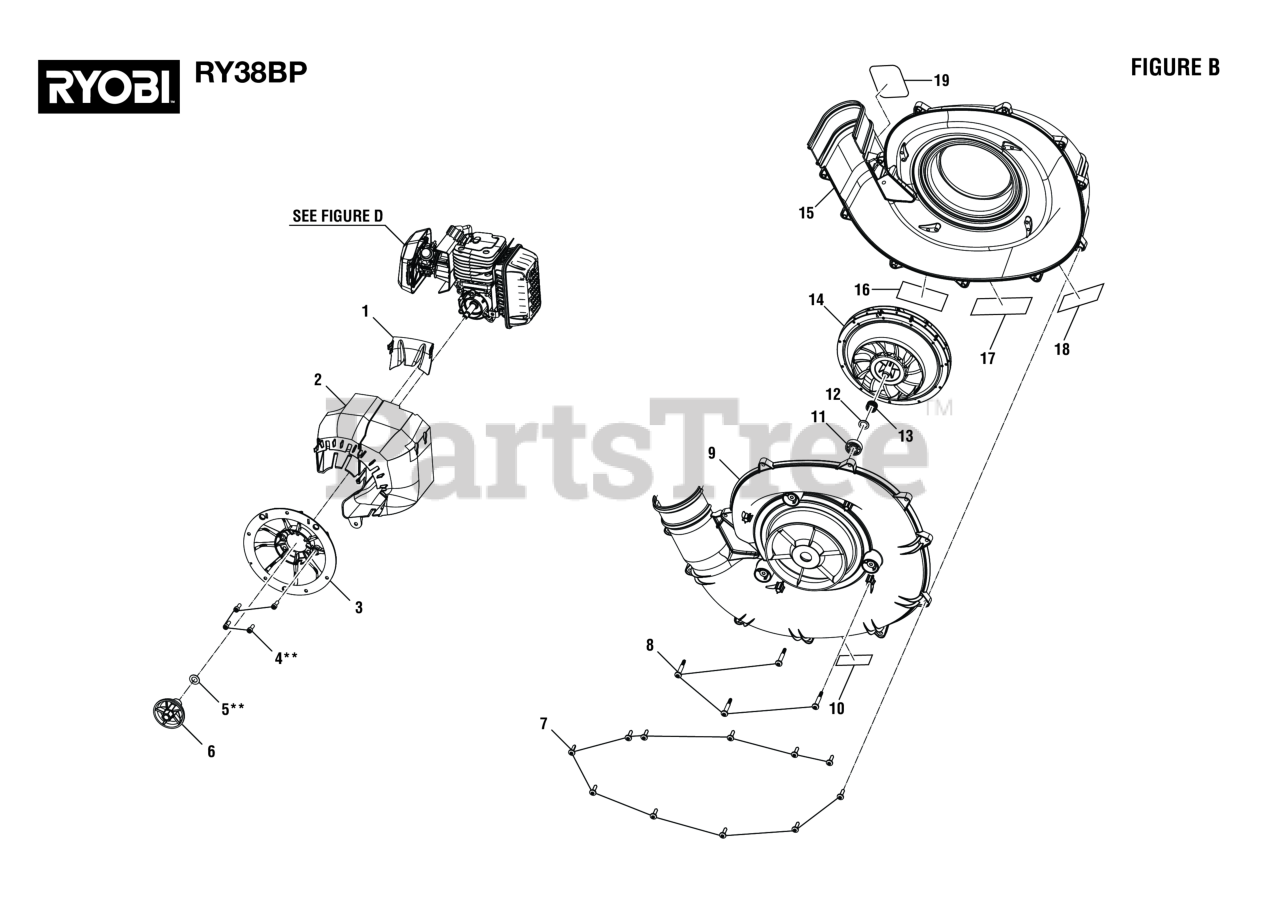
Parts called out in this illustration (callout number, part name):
1	Engine Air Guide
2	Engine Air Duct
3	Engine Mount
4	Bolt (M5 x 14 mm)
5	Washer (Oil Pump Drive Gear)
6	Fan Drive Coupler
7	Screw (10-14 x 19 mm, T25 Torx Truss Pan Hd. T.F.)
8	Shoulder Screw (M5 x 40 mm, T25 Torx Truss Hd. T.F.)
9	Outer Volute w/Bearing and Label
10	Hair Ingestion Warning Label
11	Ball Bearing (6001-zz)
12	Washer (OD18 x ID12.15 x 1.5t)
13	Wave Spring
14	Fan Assembly
15	Inner Volute w/Labels
16	MPH Label
17	Ryobi Logo Label
18	CFM Label
19	Warning Icon Label
